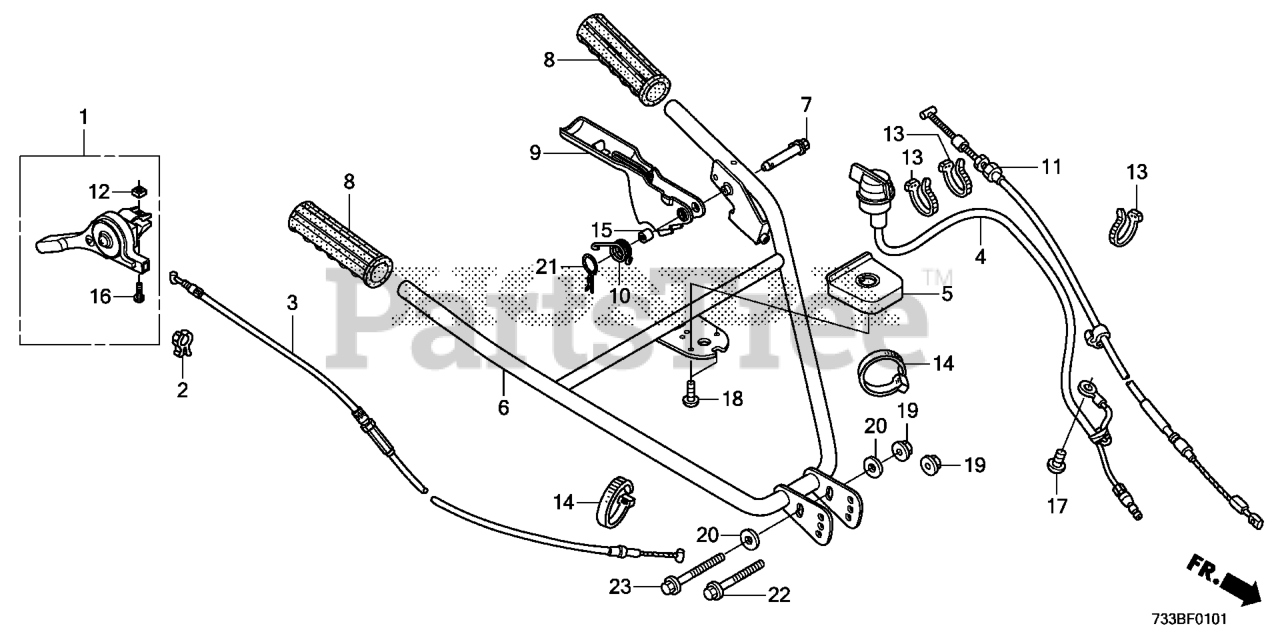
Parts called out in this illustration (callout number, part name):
1	LEVER ASSY., THROTTLE (RESIN MOLDED LEVER)
2	CLIP, THROTTLE (RESIN MOLDED CLIP)
3	CABLE, THROTTLE
4	SWITCH ASSY., ENGINE STOP
5	COVER, ENGINE STOP SWITCH
6	PIPE, HANDLE
7	PIN, CLUTCH LEVER
8	GRIP, HANDLE
9	LEVER, CLUTCH
10	SPRING, CLUTCH LEVER RETURN
11	CABLE, MAIN CLUTCH
12	NUT, SQUARE (5MM)
13	BAND, HARNESS (BLACK)
14	BAND, CABLE (120MM) (BLACK)
16	SCREW, PAN (5X20)
17	SCREW, PAN (6X10)
18	SCREW, TAPPING (5X14) (PO)
19	NUT, FLANGE (10MM)
20	WASHER, PLAIN (10MM)
21	PIN, LOCK (8MM)
22	BOLT, FLANGE (10X80)
23	BOLT, FLANGE (10X85)
